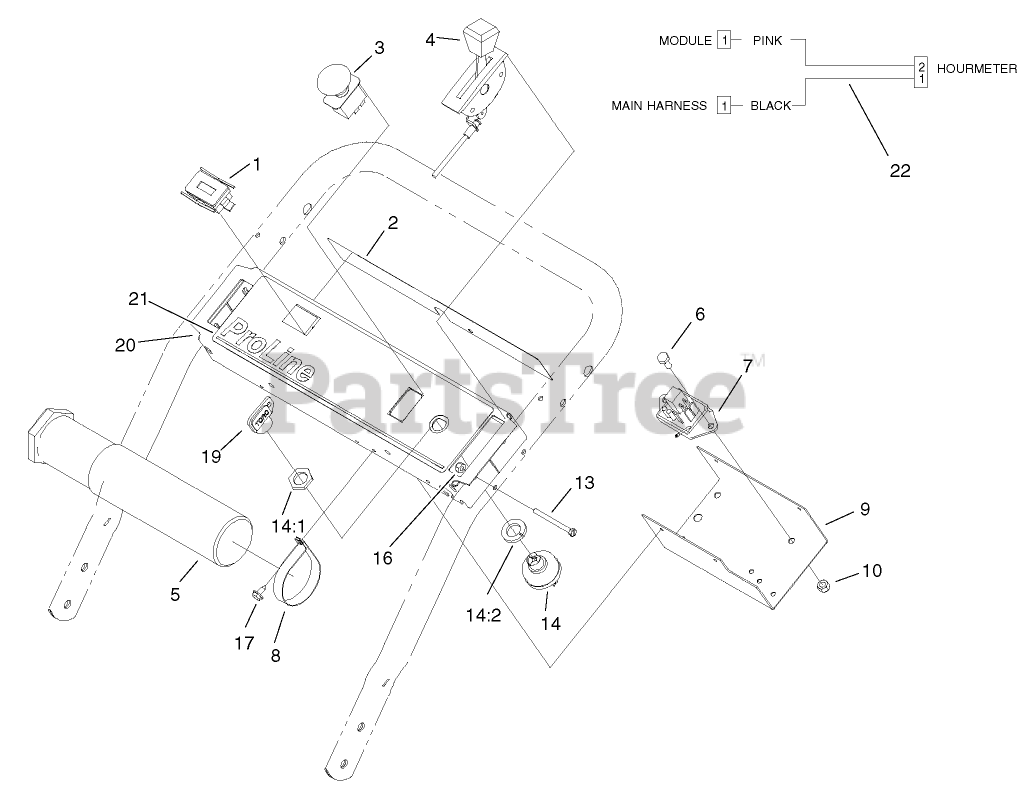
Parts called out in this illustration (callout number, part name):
1	HOURMETER
2	DECAL-WARNING
3	SWITCH-PTO
4	CONTROL-THROTTLE
5	TUBE-MANUAL
6	SCREW-HH
7	MODULE-DELAY
8	CLAMP-R
9	PANEL-BOTTOM
10	NUT-LOCK, NI
13	SCREW-SHH
14	SWITCH-ON / OFF
14:1	NUT-HH
14:2	WASHER-TOOTH, INTERNAL
16	NUT-LOCK, NI
17	SCREW-HWHTF
19	KEY-IGNITION
20	PANEL-CONTROL
21	DECAL-PANEL, CONTROL
